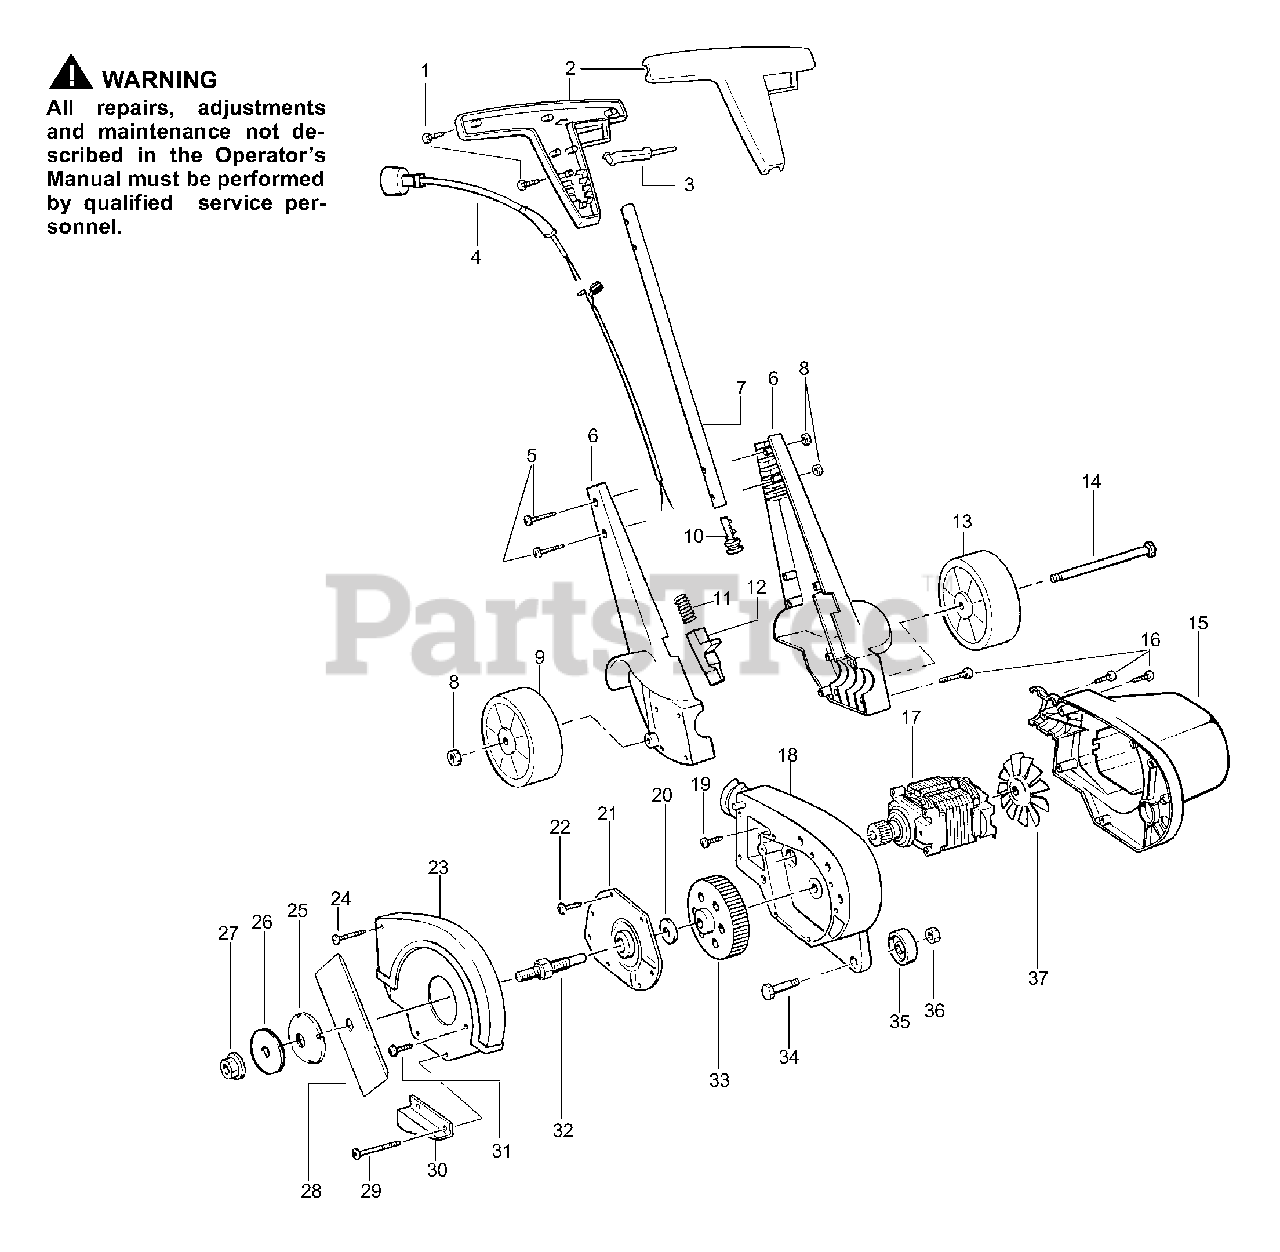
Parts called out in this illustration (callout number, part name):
1	Screw
2	Handle Set
3	Trigger Switch Lever
4	Harness/Power Cord Ass'y.
6	Rear Housing
7	Handle Tube
9	Rear Wheel
10	Protector Harness
11	Spring Slide
12	Slide Release
13	Rear Wheel
14	Assy-Rear Axle
15	Motor Housing
16	Screw
17	Assy-Motor
18	Deck Frame Ass'y.
21	Bearing Holder Ass'y.
23	Blade Shield
25	Spring-Clutch Type 1
25	Spring-Clutch Type 2
26	Washer-Cup Type 1
26	Washer-Cup Type 2
27	Nut-Blade Type 1
27	Nut-Blade Type 2
30	Edge Guide
32	Shaft Type 1
32	Shaft Type 2
33	Drive Gear
35	Front Roller
37	Fan Motor
